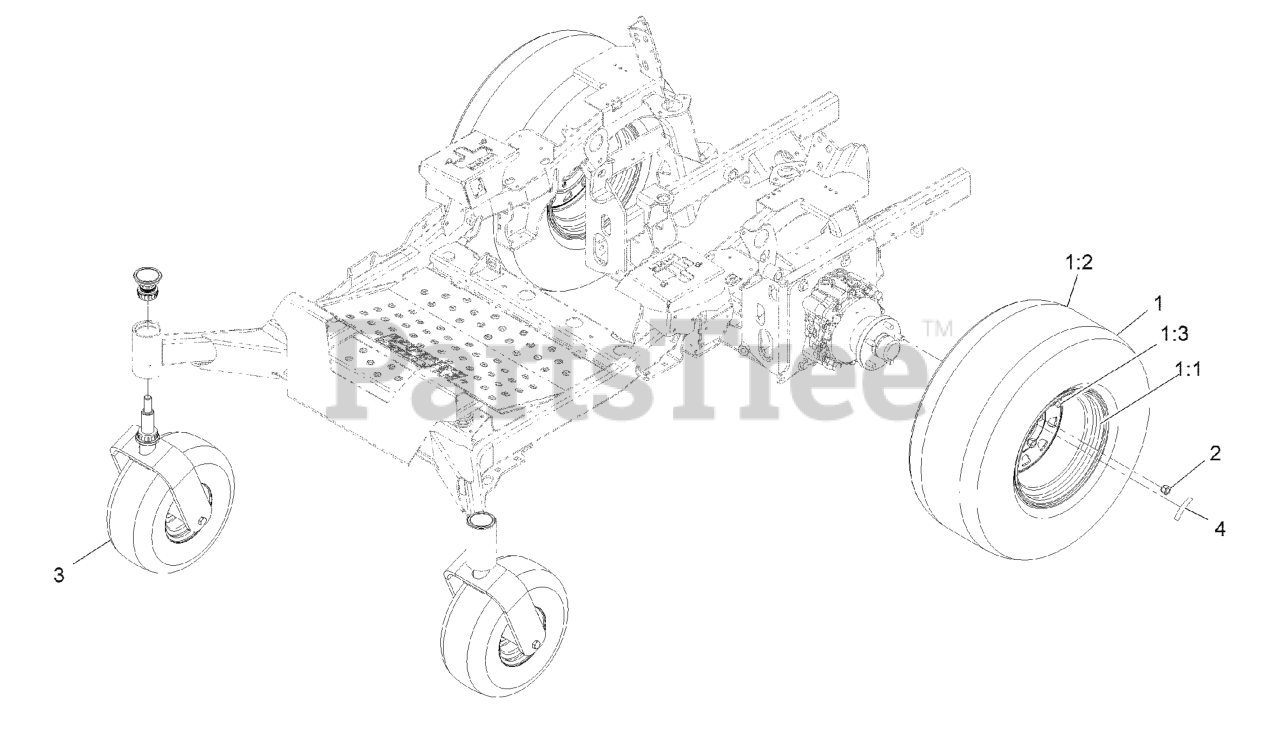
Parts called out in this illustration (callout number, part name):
1	ASM-TIRE 26X12-12, 1.0 OFFSET
1:1	RIM ASM, 1.0 OFFSET
1:3	Stem-Valve
2	NUT-LUG
3	ASM, Wheel Caster
4	DECAL-TORQUE, WHEEL NUT
